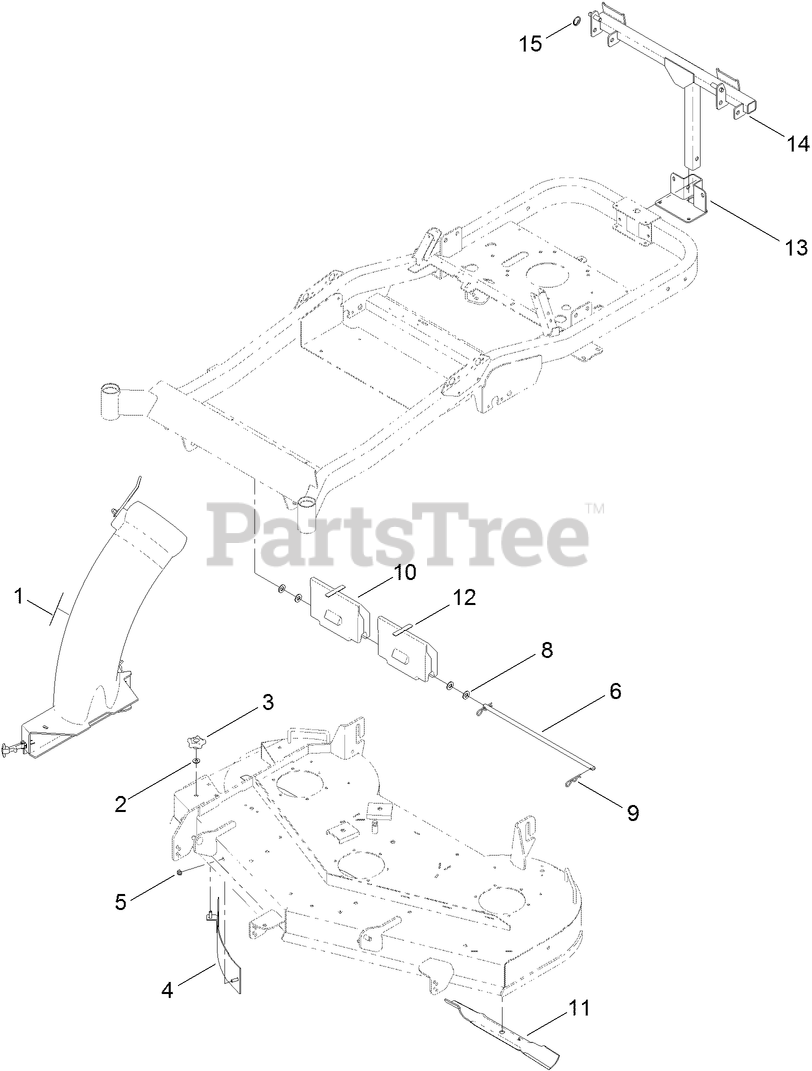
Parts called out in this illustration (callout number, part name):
1	CHUTE ASM
2	WASHER-FLAT
3	KNOB-LOCKING
4	BAFFLE-BAGGER
5	NUT-HF, NI
6	ROD-DECK, PIVOT
8	WASHER-FLAT
9	PIN-HAIR
10	WEIGHT-BAGGER
11	BLADE-HI LIFT, 18.75 INCH
12	BUMPER-PAD
13	SUPPORT-BAGGER
14	FRAME-PIVOT
15	PIN-COTTER, CIRCULAR
